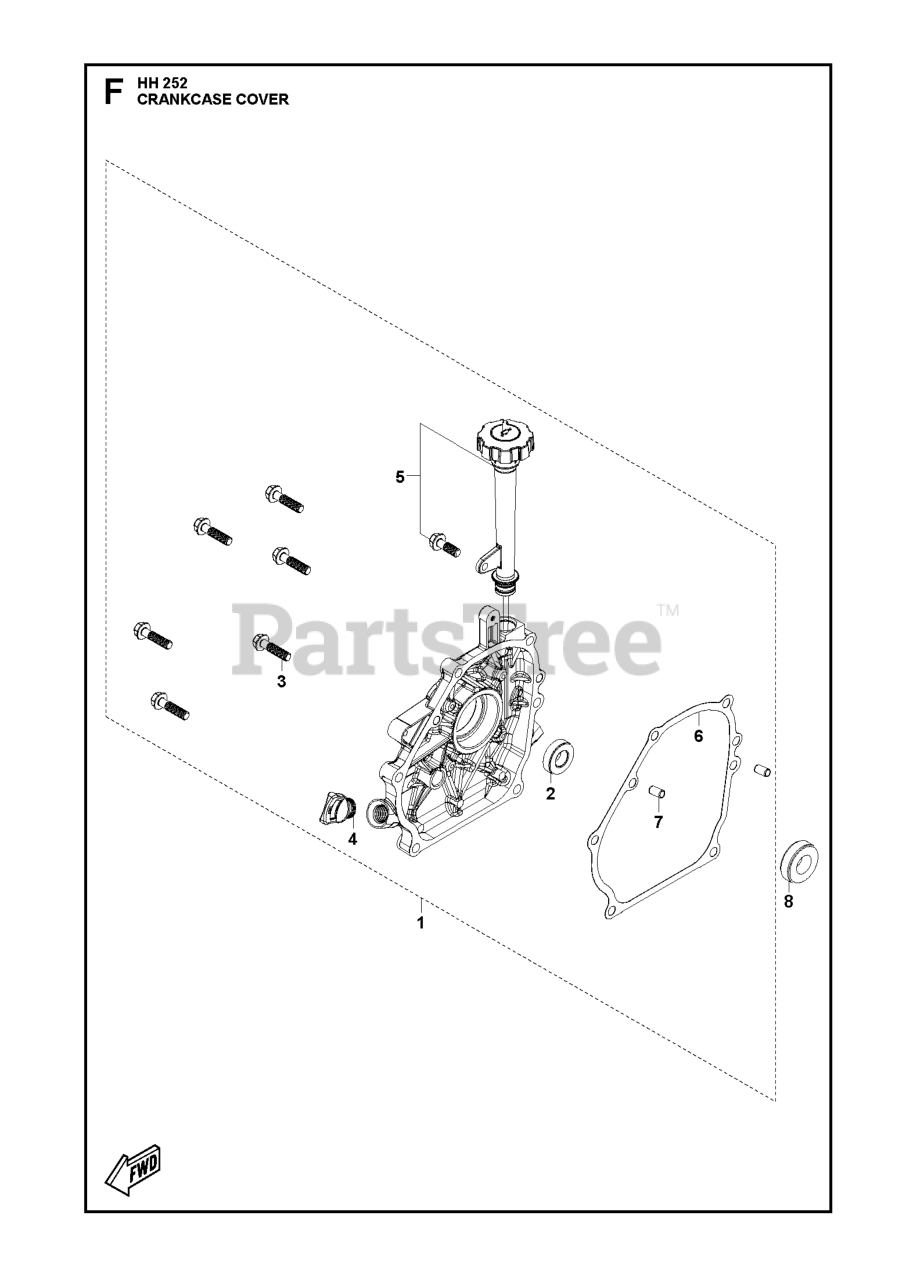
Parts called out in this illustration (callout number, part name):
1	COVER KIT CRANKCASE COVER
2	SEAL OIL SEAL
3	BOLTS
5	DIPSTICK DIPSTICK KIT
6	GASKET CRANKCASE COVER GASKET
7	PIN LOCATION PIN
8	BALL BEARING
